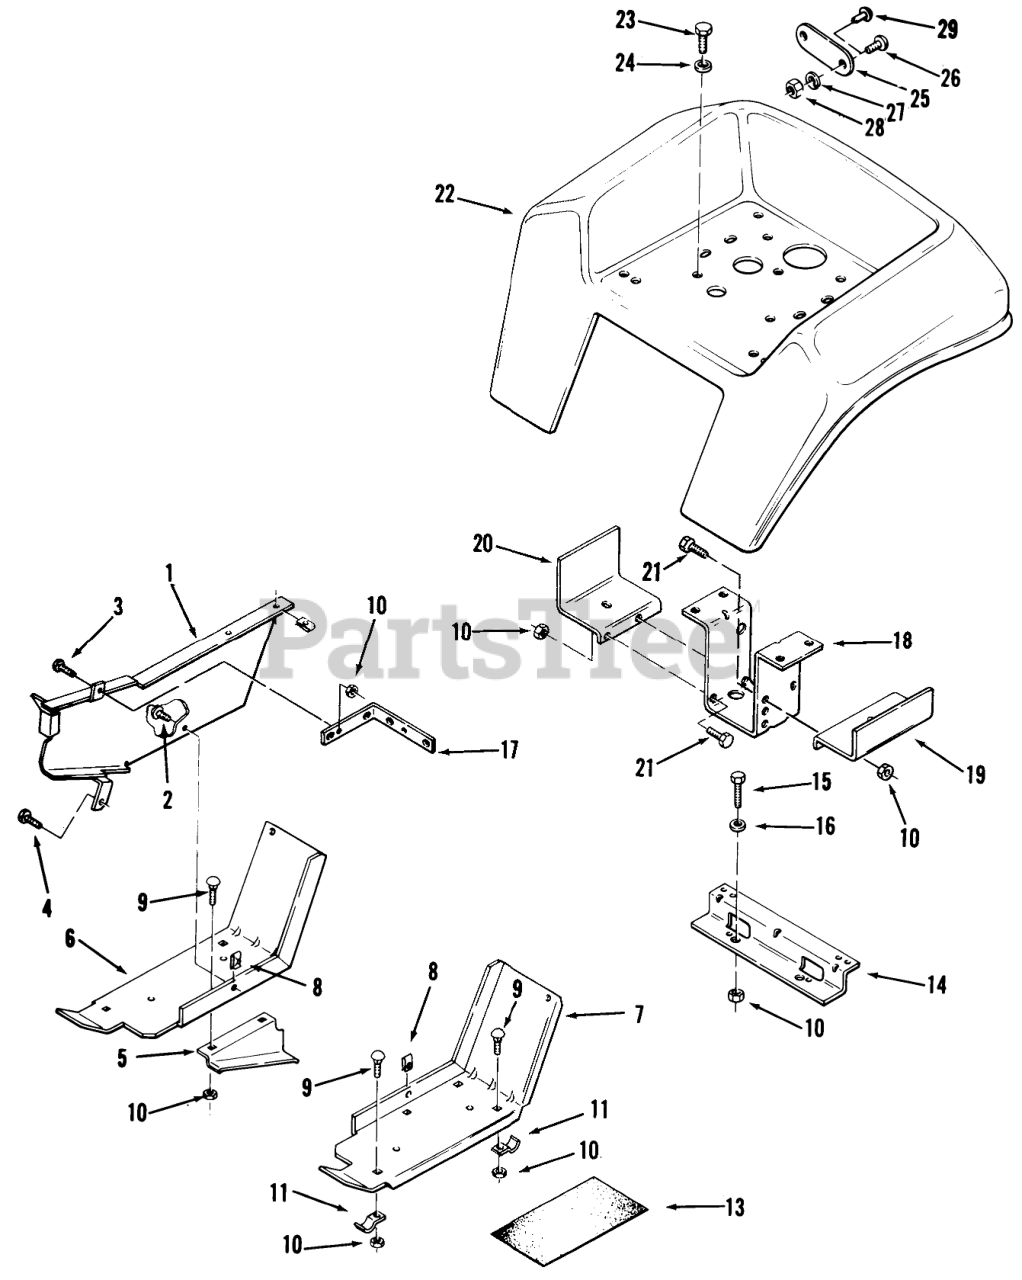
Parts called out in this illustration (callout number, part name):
1	ASSY-BELT GUARD 8 R
1	Belt Guard
2	Screw
3	Bolt
4	SCREW
5	GUID-LOWER BLTR
6	Footrest-RH
7	FOOTREST LH R
9	CARRIAGE BOLT -4
10	Nut
11	BRACKET
13	PAD-FOOTREST
14	BRACKET-FENDER B
15	Bolt
16	WASHER 5/16 SAE
17	SUPPORT-BELT GUAR B
17	Support Bracket-Belt Guard C-175 Twin Only
18	Bracket-Fender Support
19	Fuel Tank Support LH
20	Support-FueITank RH
21	Bolt
22	Fender
23	Bolt
24	Collar
25	REFLECTOR-STICK ON
26	Screw
27	Lockwasher
28	Nut
29	Poprivet
